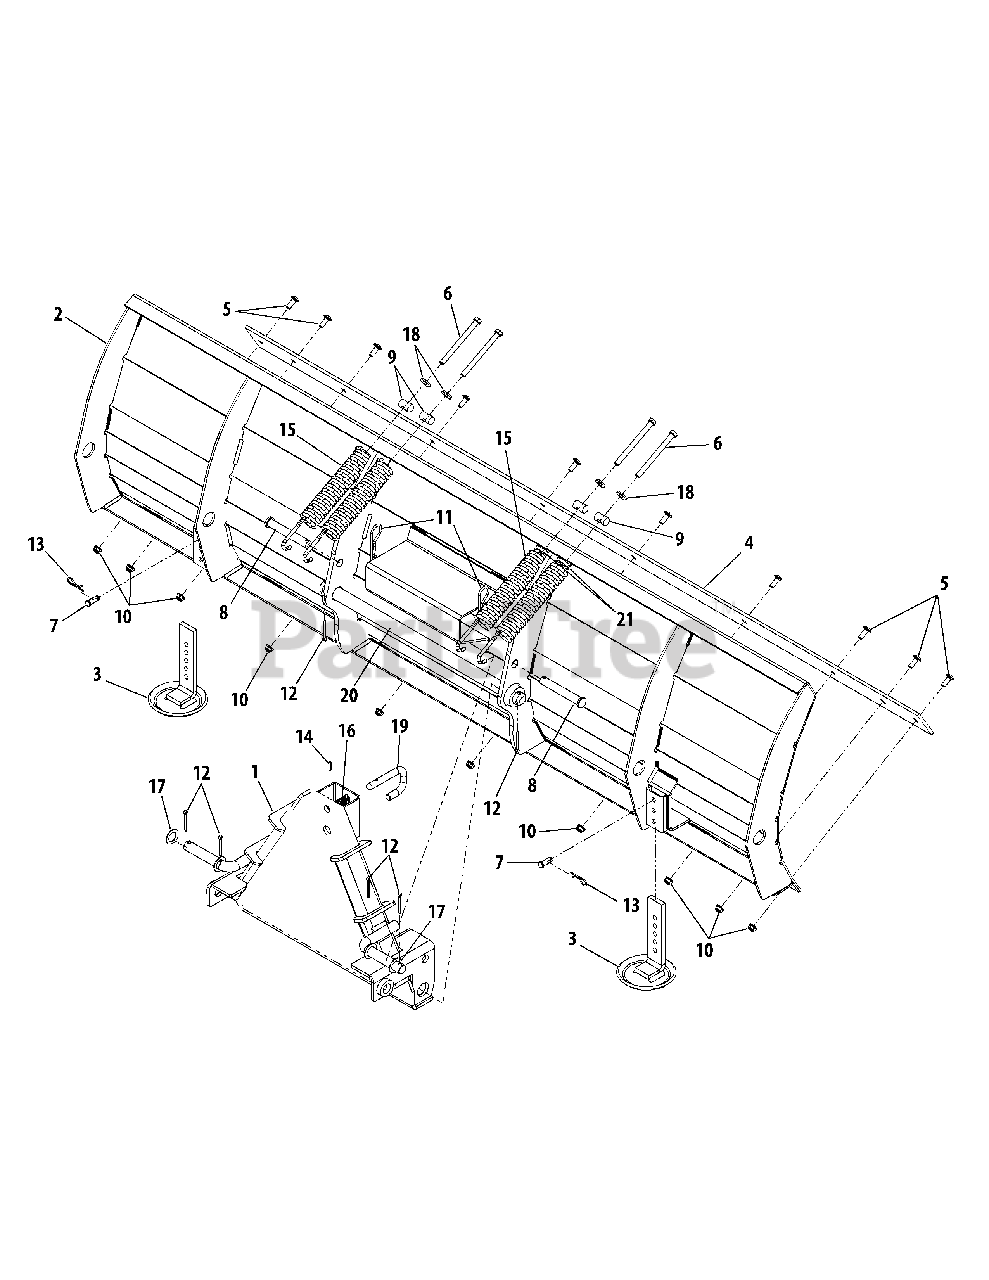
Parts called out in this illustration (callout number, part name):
1	Frame, Blade Mounting
2	Blade Assembly
3	Shoe, Skid
4	Blade, Scraper
5	Bolt, Carriage, 5/16-18 x .875
6	Screw, Hex Cap, 3/8-16 x 4.25 Gr5
7	Pin, Clevis, .375 x .969
8	Pin, Clevis, .625 x 4.25
9	Roller, Spring
10	Nut, Hex Insert Flnge Lock, 5/16-18 Gr F
11	Pin, Internal Cotter
12	Pin, Cotter, 3/16 x 1.5
13	Pin, Internal Cotter
14	Pin, Spirol, 3/16 x 3/4
15	Spring, Adjustment
16	Spring, Compression, .57 x 2.09
17	Washer, Flat, 1.0 x 1.75 x .107
18	Washer, Flat, .406 x .875 x .105
19	Pin, Front Hitch
20	Rod, Blade Pivot
21	Insert, Spring
